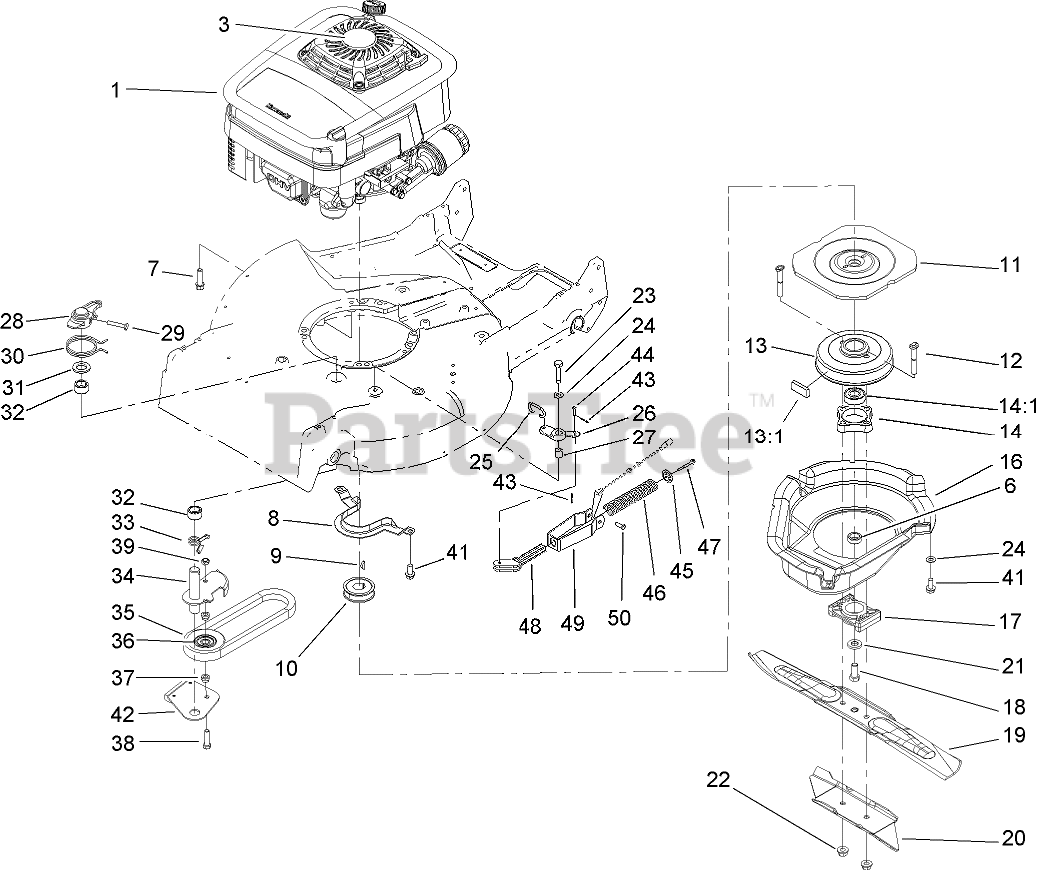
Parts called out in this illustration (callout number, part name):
1	ENGINE ASM
3	DECAL
6	SPACER-SHAFT, OUTPUT
7	SCREW-TAPTITE
8	BRACKET-GUIDE, BELT
9	KEY-WOODRUFF
10	PULLEY-DRIVER
11	FLYWHEEL-BBC
12	BOLT-BLADE
13	BRAKE DRUM ASM
13:1	DAMPENER-VIBRATION
14	HUB ASM
14:1	BEARING-BALL
16	SHIELD
17	SPACER-BLADE
18	SCREW-HH
19	BLADE-21 INCH
20	STIFFENER-BLADE
21	WASHER-SPRING
22	NUT-LOCK
23	SCREW-HH
24	WASHER-PLAIN
25	LINK-CONTROL
26	BELLCRANK
27	SLEEVE-BELLCRANK
28	LEVER
29	SCREW-HH
30	SPRING-TORSION
31	WASHER
32	BEARING
33	SPRING-TORSION
34	ARM-IDLER
35	V-BELT
36	PULLEY-IDLER
37	SPACER-PULLEY, IDLER
38	SCREW-HH
39	NUT-LOCK, NI
41	SCREW-HWHTF
42	BRAKE PLATE ASM
43	PIN-COTTER
44	PIN-SPRING
45	RETAINER-SPRING
46	SPRING
47	SCREW-HWHTF
48	GUIDE-SPRING
49	BRACKET-SPRING
50	PIN-CABLE
